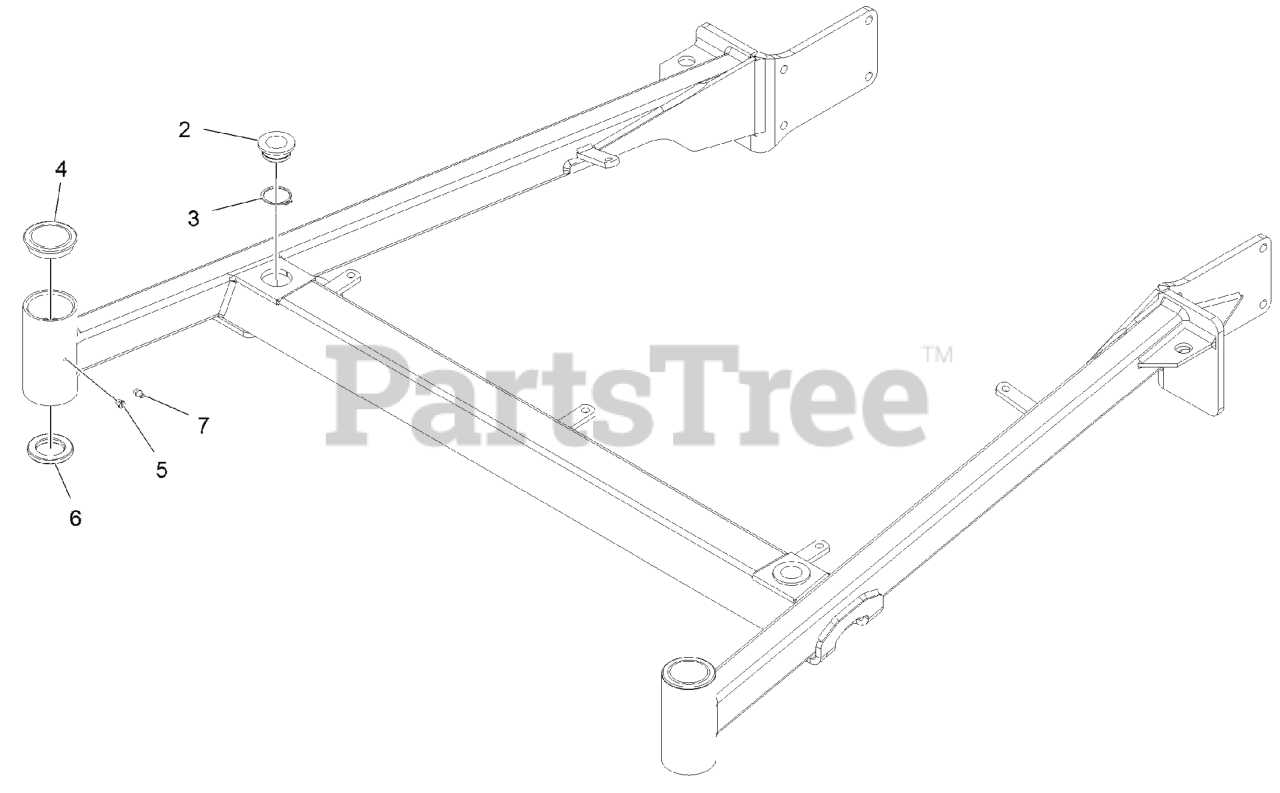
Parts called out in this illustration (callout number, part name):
2	BUSHING-DECK
3	RING-RETAINING
4	CAP-GREASE
6	SEAL-GREASE
7	FITTING-GREASE
